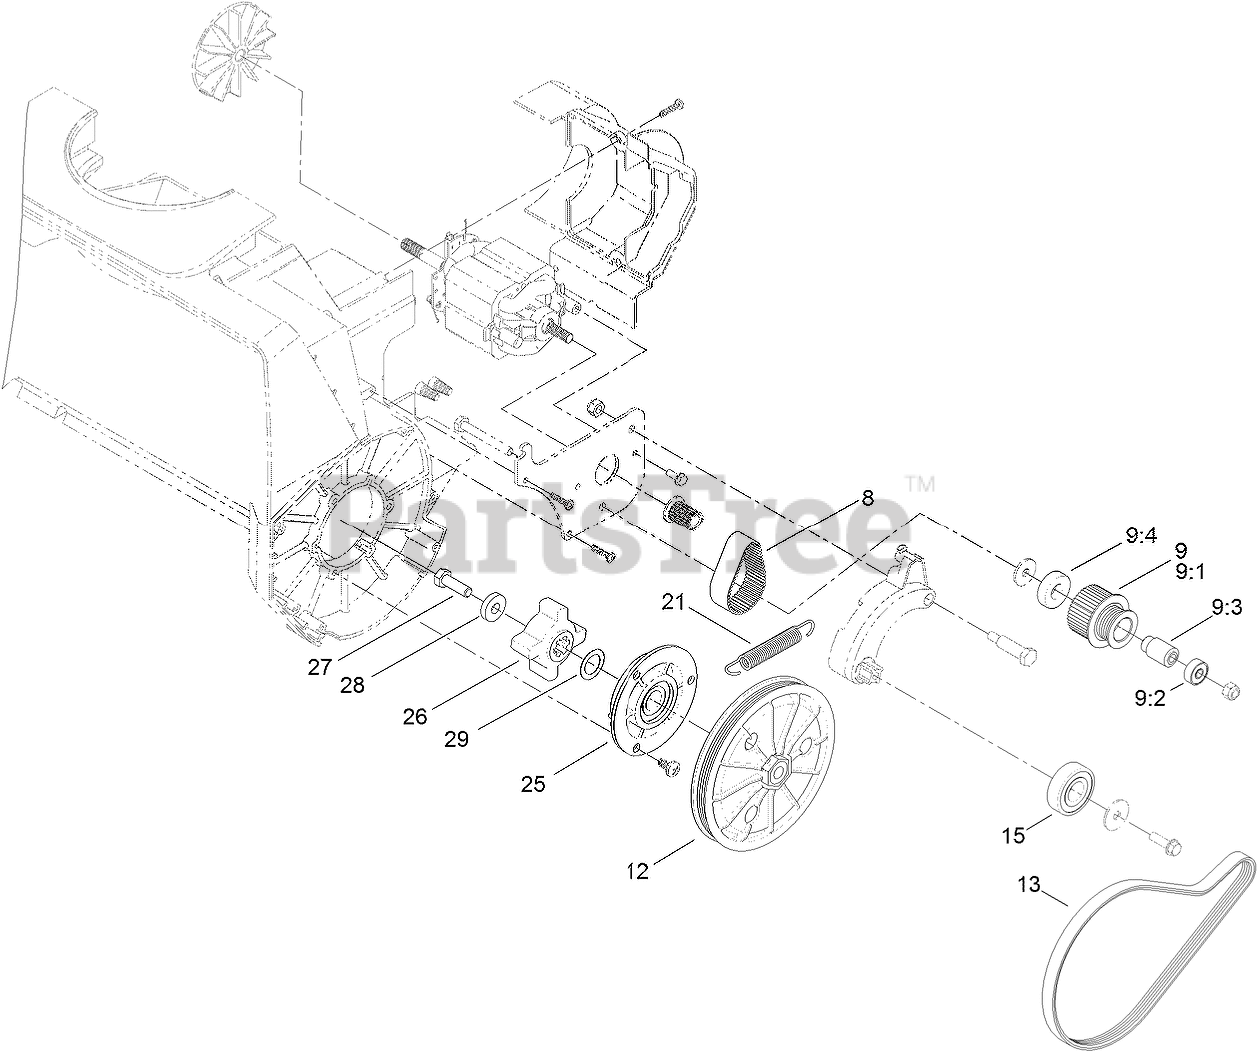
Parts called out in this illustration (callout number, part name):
8	BELT-PULLEY, IDLER/DRIVER
9	IDLER PULLEY ASM
9:1	PULLEY-IDLER
9:2	BEARING-BALL
9:3	SPACER-PULLEY, IDLER
9:4	BEARING-BALL
12	PULLEY ASM
13	BELT-DRIVE
15	BEARING-BALL
21	SPRING-IDLER
25	PILLOW BLOCK ASM
26	COUPLER-PULLEY
27	SCREW-HH
28	SPACER
29	WASHER
